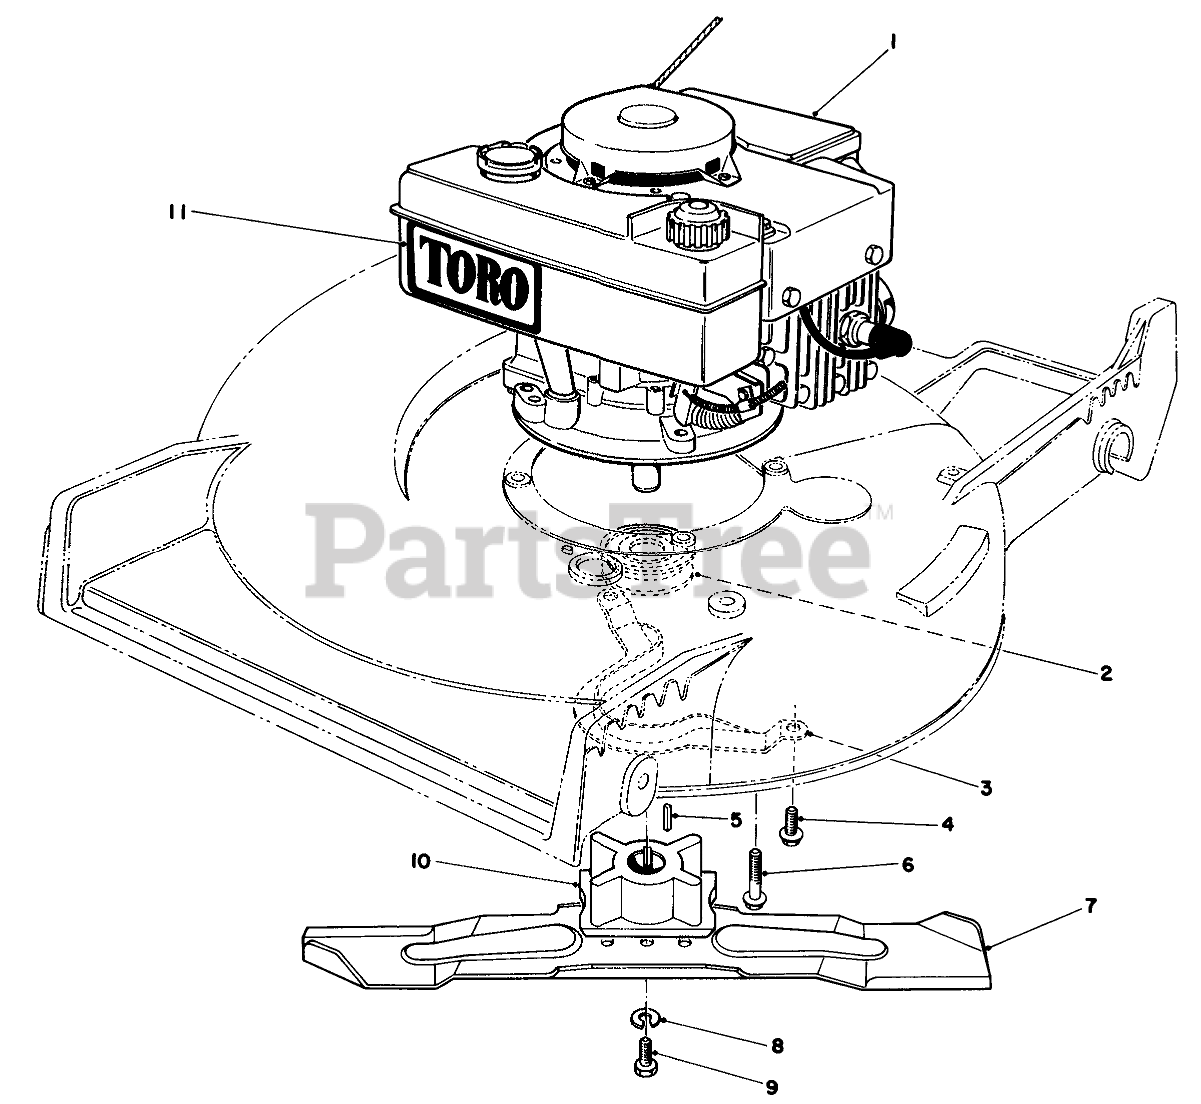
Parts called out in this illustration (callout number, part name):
1	Engine
2	Pulley
3	BELT GUIDE
4	Screw
5	KEY-SQUARE
6	3/8-16 X 2 CAPSCREW
7	BLADE-21in
8	SCREW-BLADE
9	WASHER-LOCK
10	BLADE RETAINER(DEEP)
11	Decal Tow
